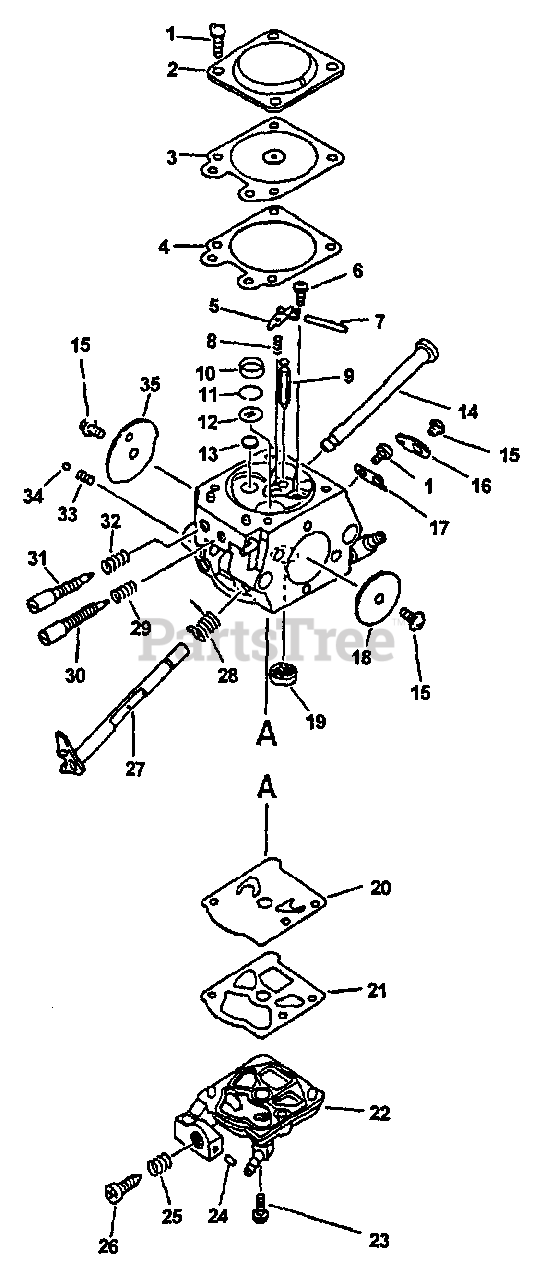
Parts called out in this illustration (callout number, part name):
1	REPAIR KIT, CARBURETOR
2	COVER, METERING DIAPHRAGM
3	REPAIR KIT, CARBURETOR
3	GASKET / DIAPHRAGM KIT
4	GASKET, METERING
5	LEVER, METERING
6	SCREW, METERING LEVER PIN
7	PIN, METERING LEVER
8	SPRING, METERING LEVER
9	VALVE, INLET NEEDLE
10	PLUG, WELCH
11	RING, RETAINING
12	SCREEN, SPARK ARRESTER
13	PLUG, WELCH
14	SHAFT, CHOKE
16	LEVER, THROTTLE
17	CLIP, THROTTLE SHAFT
18	VALVE, THROTTLE
19	STRAINER
22	COVER, FUEL PUMP
24	PLUG, FRICTION
26	SCREW, IDLE ADJUST
27	SHAFT, THROTTLE
28	SPRING, THROTTLE RETURN
30	NEEDLE, IDLE
31	NEEDLE, HIGH SPEED
34	BALL, CHOKE FRICTION
35	VALVE, CHOKE
